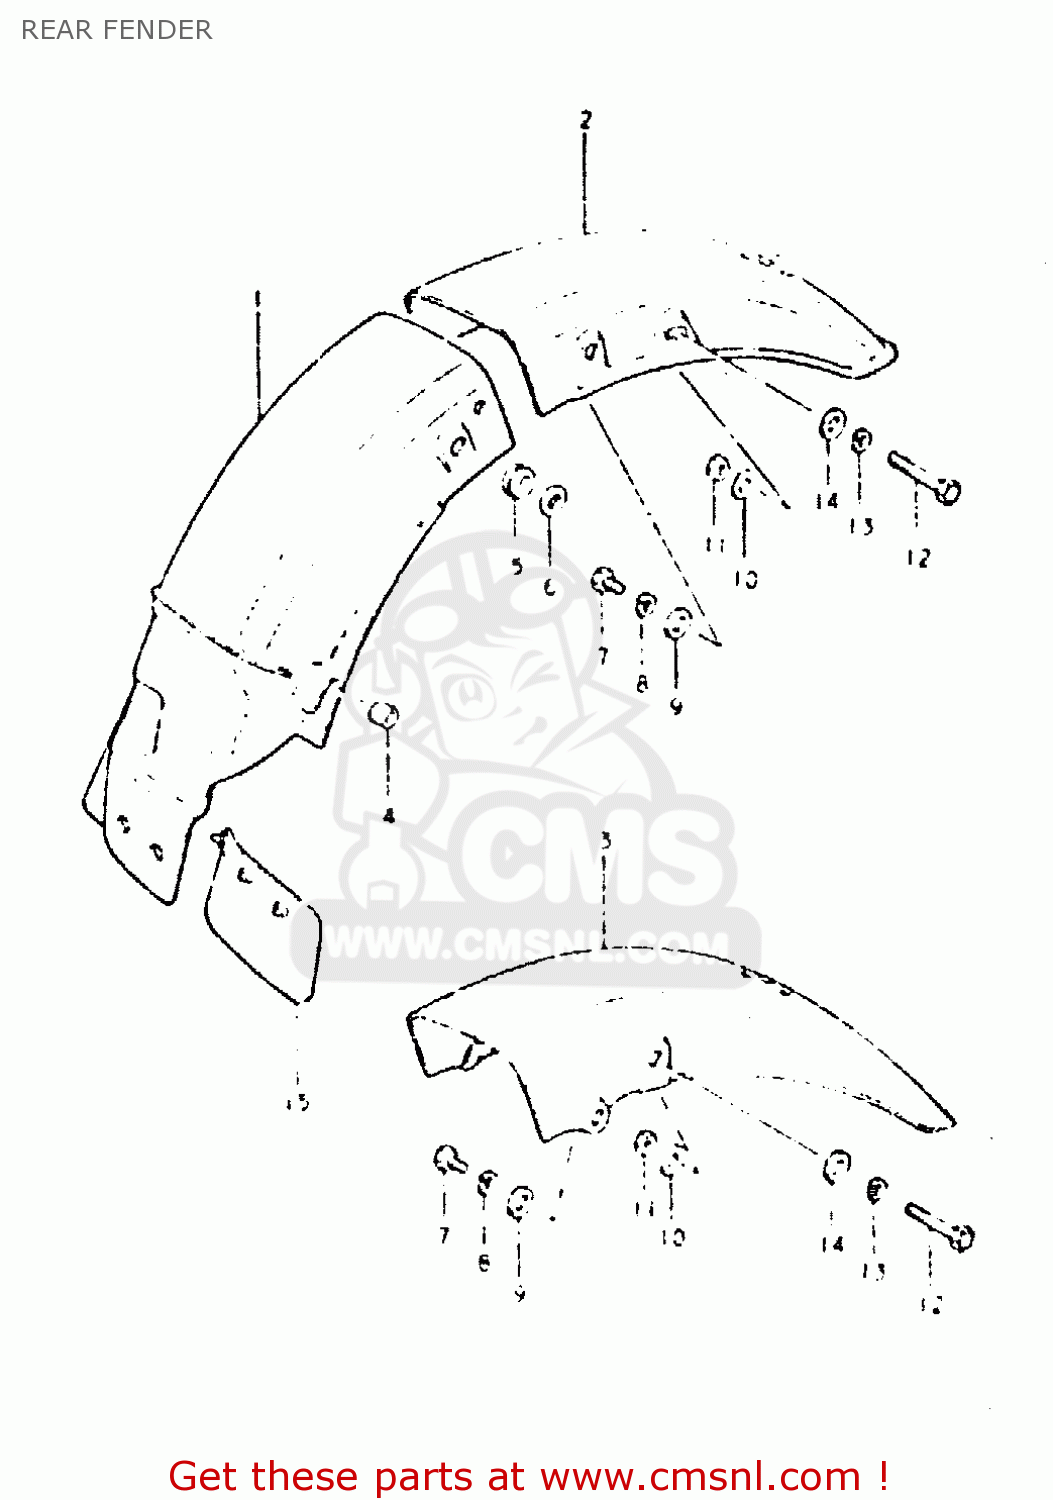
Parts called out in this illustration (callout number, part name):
1	BODY,REAR FENDER,FRONT
2	BODY, REAR FENDER REAR
4	CUSHION
5	CUSHION
6	WASHER
7	BOLT 8X12
8	LOCK WASHER
9	WASHER
10	WASHER
11	NUT 8MM
12	BOLT
13	LOCK WASHER
14	WASHER
15	GUIDE,RR FENDER MUD
